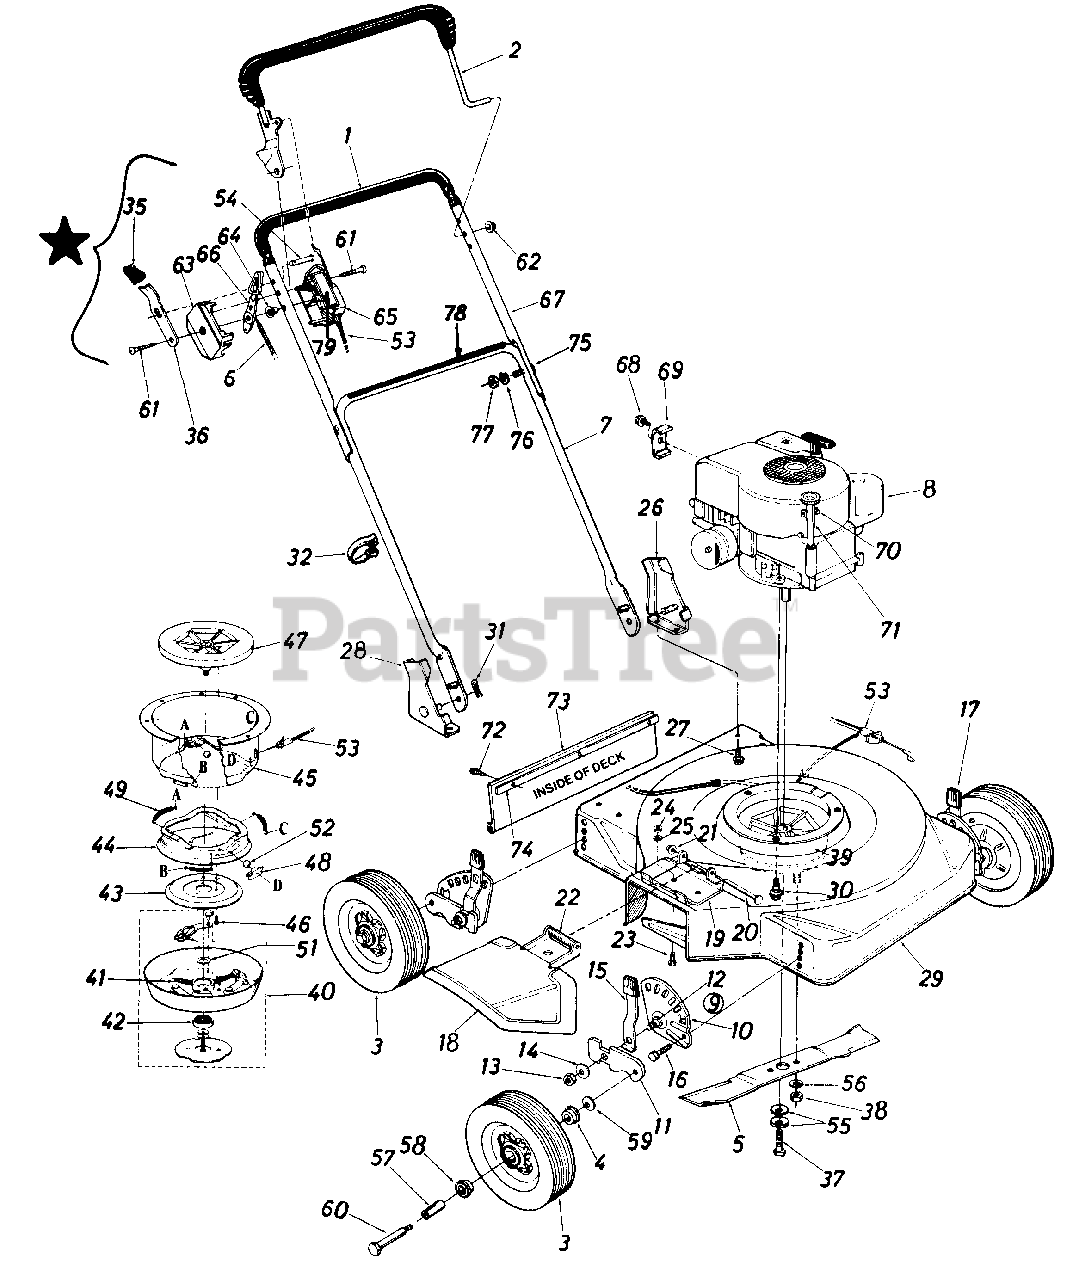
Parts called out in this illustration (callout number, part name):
2	Control Handle Ass'y. - R.H.
3	Wheel Ass'y. Comp. 8.0 x 1.75
4	Flange Ball Bearing 3/8" I.D.
5	20" Blade
6	Throttle Control Wire 39.0" - Red
7	Lower Handle
8	Engine
9	Height Adjuster Ass'y. - R.H.
10	Index Plate Ass'y. - R.H.
11	Pivot Bar
12	Shoulder Bolt
13	Hex Ins. L-Nut 3/8-24 Thd.
14	Bell-Wash. .400" I.D. x 1.13" O.D.
15	Spring Lever W/Knob
16	Hex Sems Bolt 3/8-16 x .62" Lg.
17	Height Adjuster Ass'y. - L.H.
18	Chute Deflector Ass'y. Comp.
19	Adapter Plate
20	Pivot Pin
21	Push Nut 1/4" Rod
22	Torsion Spring
23	Hex Bolt 1/4-20 x .50" Lg.
24	Hex Nut 1/4-20 Thd.
25	L-Wash. 1/4" I.D.
26	Handle Mount Brkt. Ass'y. - L.H.
27	Hex Wash. Hd. B-Tap. Scr. 5/16-18 x .50" Lg.
28	Handle Mount Brkt. Ass'y. - R.H.
29	20" Deck Ass'y.
31	Intern. Cot. Pin 5/16" Dia.
32	Cable Tie
35	Spring Lever Knob
36	Lockout Spring
37	Hex Bolt 3/8-24 x 2.00" Lg. (Grade 8)
38	Hex Nut 3/8-24 Thd. (Grade 8)
39	Blade Brake Clutch Comp.
40	Clutch Blade Housing Ass'y.
41	Compression Spring .35" O.D. x 2.00" Lg.
42	Ball Brg. .669 I.D. x 1.574 O.D.
43	Clutching Cone
44	Brake Cup Cone
45	Clutch Housing
46	Hex Tap L-Scr. 1/4-20 x .75" Lg.
47	Fan Adapter
48	Ball Block
49	Extension Spring .35" O.D. x 1.75" Lg.
51	Fl-Wash. .690" I.D. x 1.060 O.D.
52	Steel Ball .500" Dia.
53	Clutch Cable - 46.0"
54	Lock Pin .314" Dia. x 1.70" Lg.
55	Bell-Wash. .400" I.D. x .88" O.D.
56	L-Wash. 3/8" I.D.
58	Flange Ball Bearing 1/2" I.D.
59	Bell-Wash. .400" I.D. x .88" O.D.
60	Hex Bolt 3/8-16 x 2.00" Lg.
61	Truss Mach. Scr. #12 x 1.50" Lg.
62	Cap Speed Nut 5/16" Rod
63	Control Panel Half
64	Control Disc Pin
65	Clutch Panel Half
66	Throttle Control Lever
67	Upper Handle
68	Hex "B" Tap Scr. #10 x .38" Lg.
69	Casing Clamp
70	Hex Wash. Hd. "AB" Tap Scr. #8 x .50" Lg.
71	Short Ext. Oil Fill
72	Hex Wash. Hd. "AB" Tap Scr. 1/4 x .62" Lg.
73	Rear Flap Ass'y.
74	Retainer Strip
75	Curved Carriage Bolt 5/16-18 x 1.38" Lg.
76	L-Wash. 5/16" I.D.
77	Hex Nut 5/16-18 Thd.
78	Control Label-Handle
79	Control Label-Throttle
